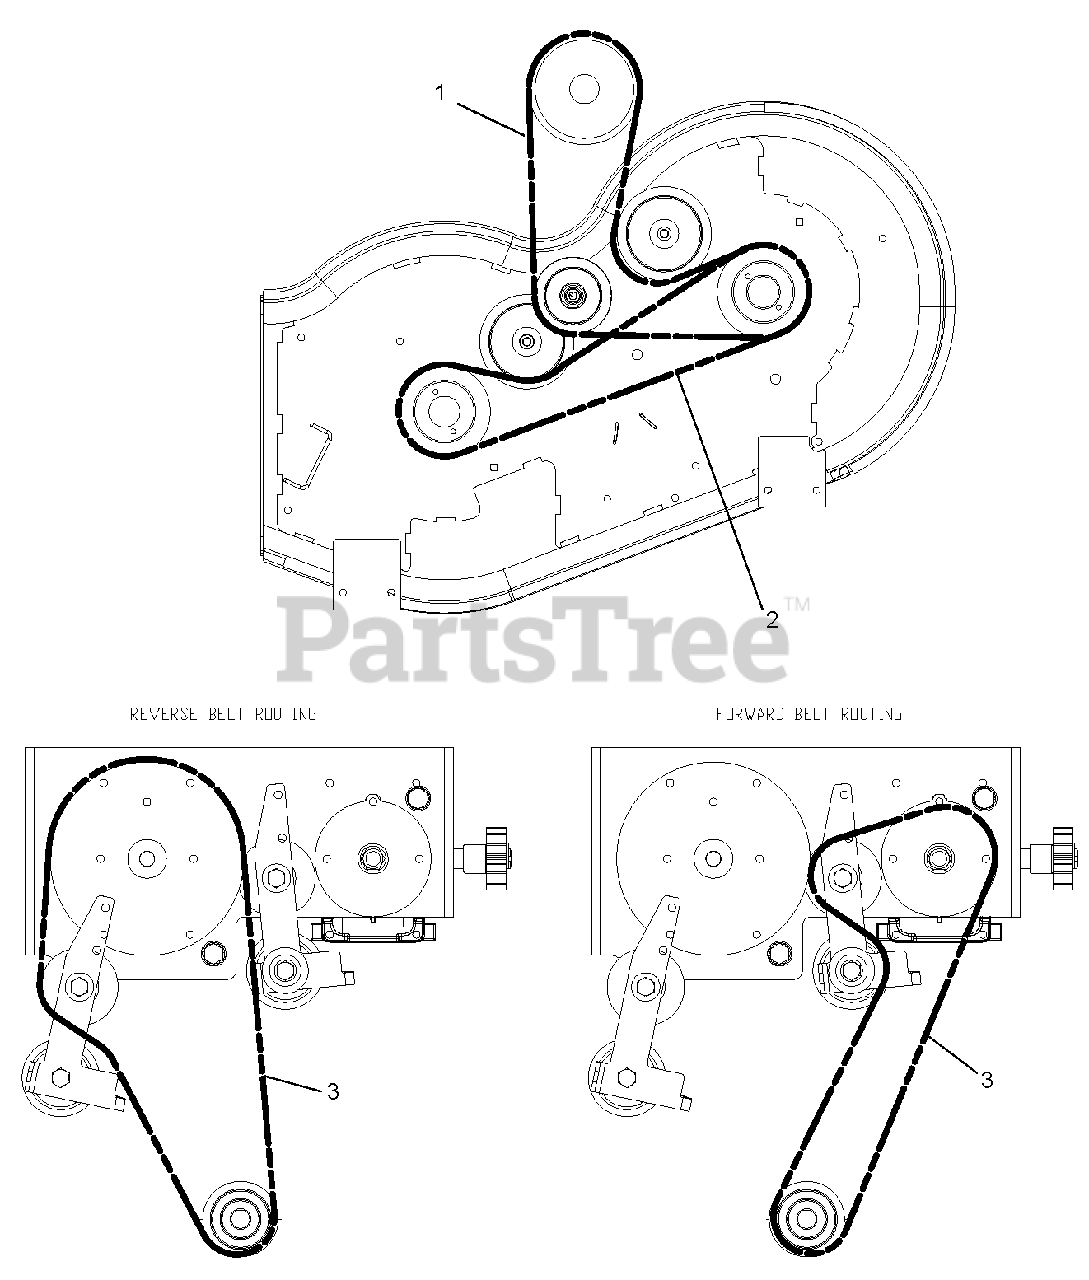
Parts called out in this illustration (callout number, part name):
1	Belt, HA 56.95 Wrapped
2	Belt, HA 51.20 Wrapped
3	Belt, 3L Wrapped
